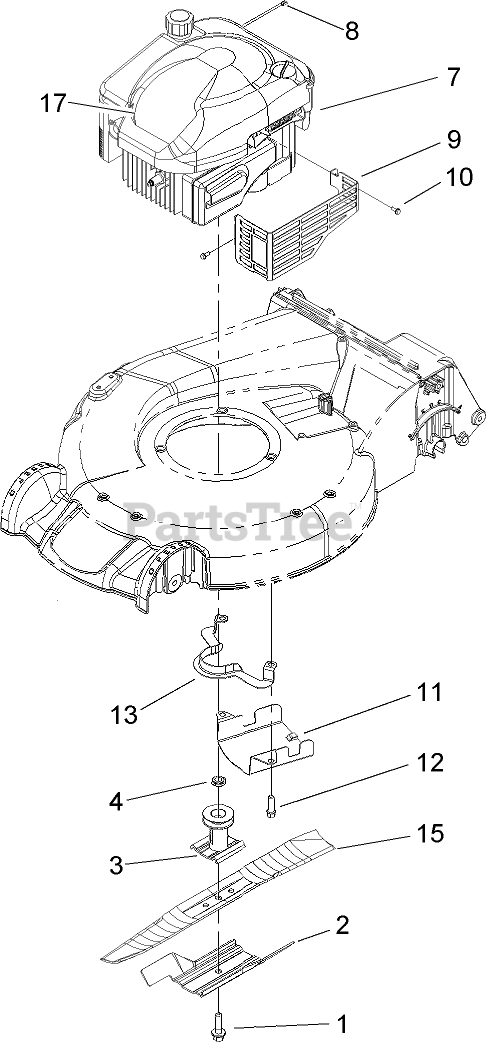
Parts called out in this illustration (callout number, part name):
1	BOLT-BLADE
2	Accelerator-Blade
3	DRIVER-BLADE
4	Spacer-Driver
8	STOP-ROPE
9	SHIELD-MUFFLER
10	SCREW-TAPTITE
11	SHIELD-GRASS
12	SCREW-TAPTITE
13	GUIDE-BELT
15	BLADE-RECYCLING
17	DECAL-RECOIL
